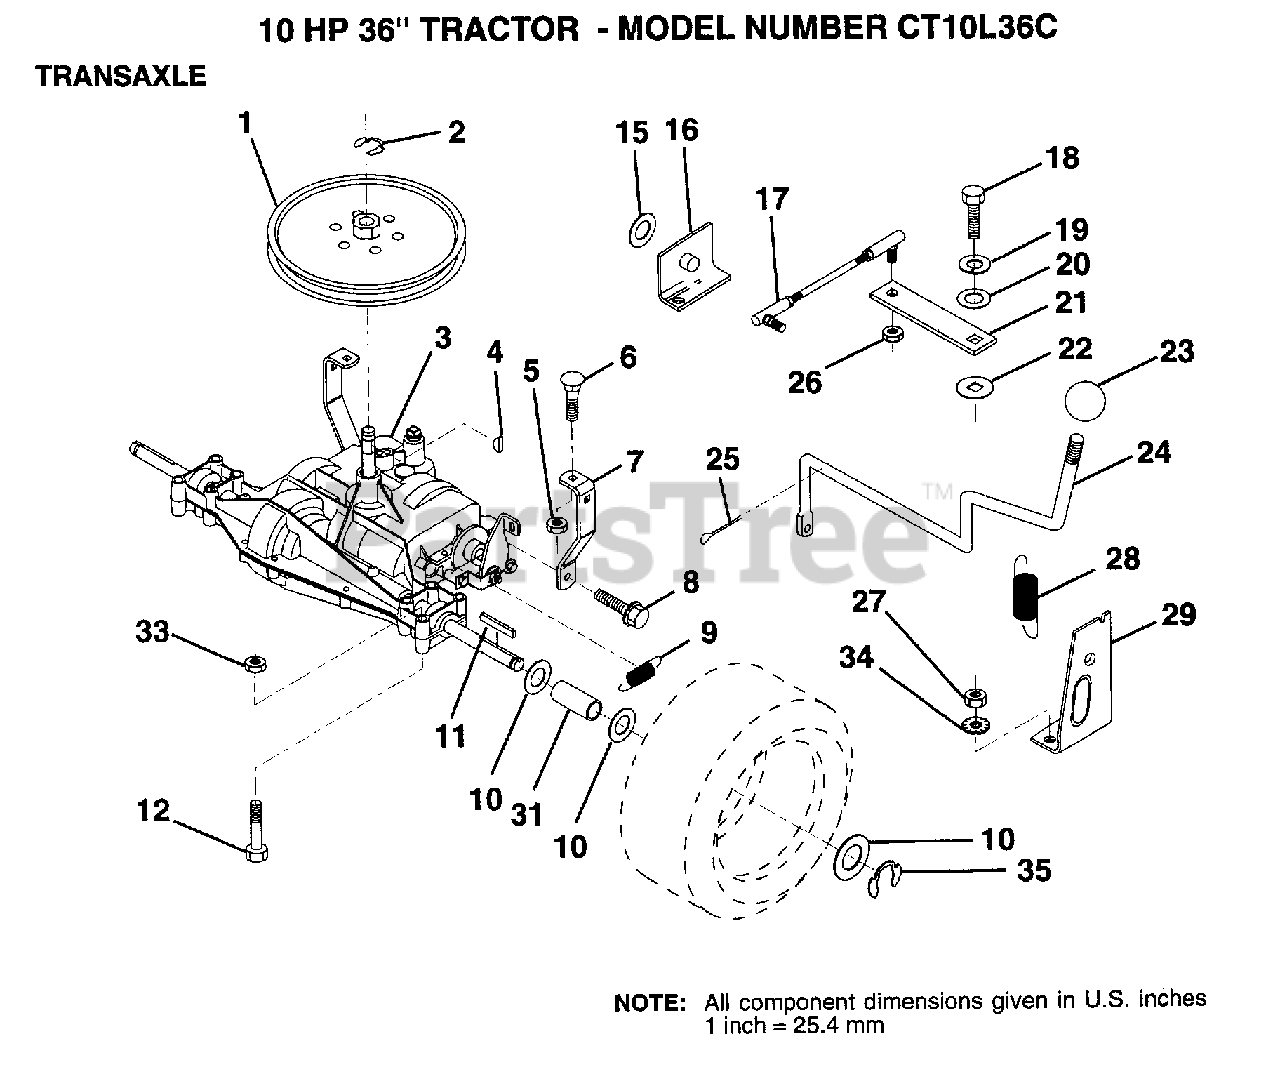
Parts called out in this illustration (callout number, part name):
1	PULLEY
5	NUT
6	BOLT
7	"STRAP,TORQUE"
7	"LINK,SHIFT"
8	SCREW
10	WASHER
11	SQUARE KEY
12	BOLT
16	"SUPT,HDLE SHT LH"
19	LOCKWASHER
20	WASHER LT
21	ARM SHIFT
22	WASH-SHFT PLT LT
23	KNOB T (1/2-HOLE)
24	"ROD,SHIFT"
25	PIN COTTER 1/8
26	NUT.LOCK.5/16-24
28	"SPRING,EXT"
29	"SUPT,HDLE RH"
31	SPACER LT
33	NUT
34	LOCKWASHER.5/16.E
35	E-RING LT
